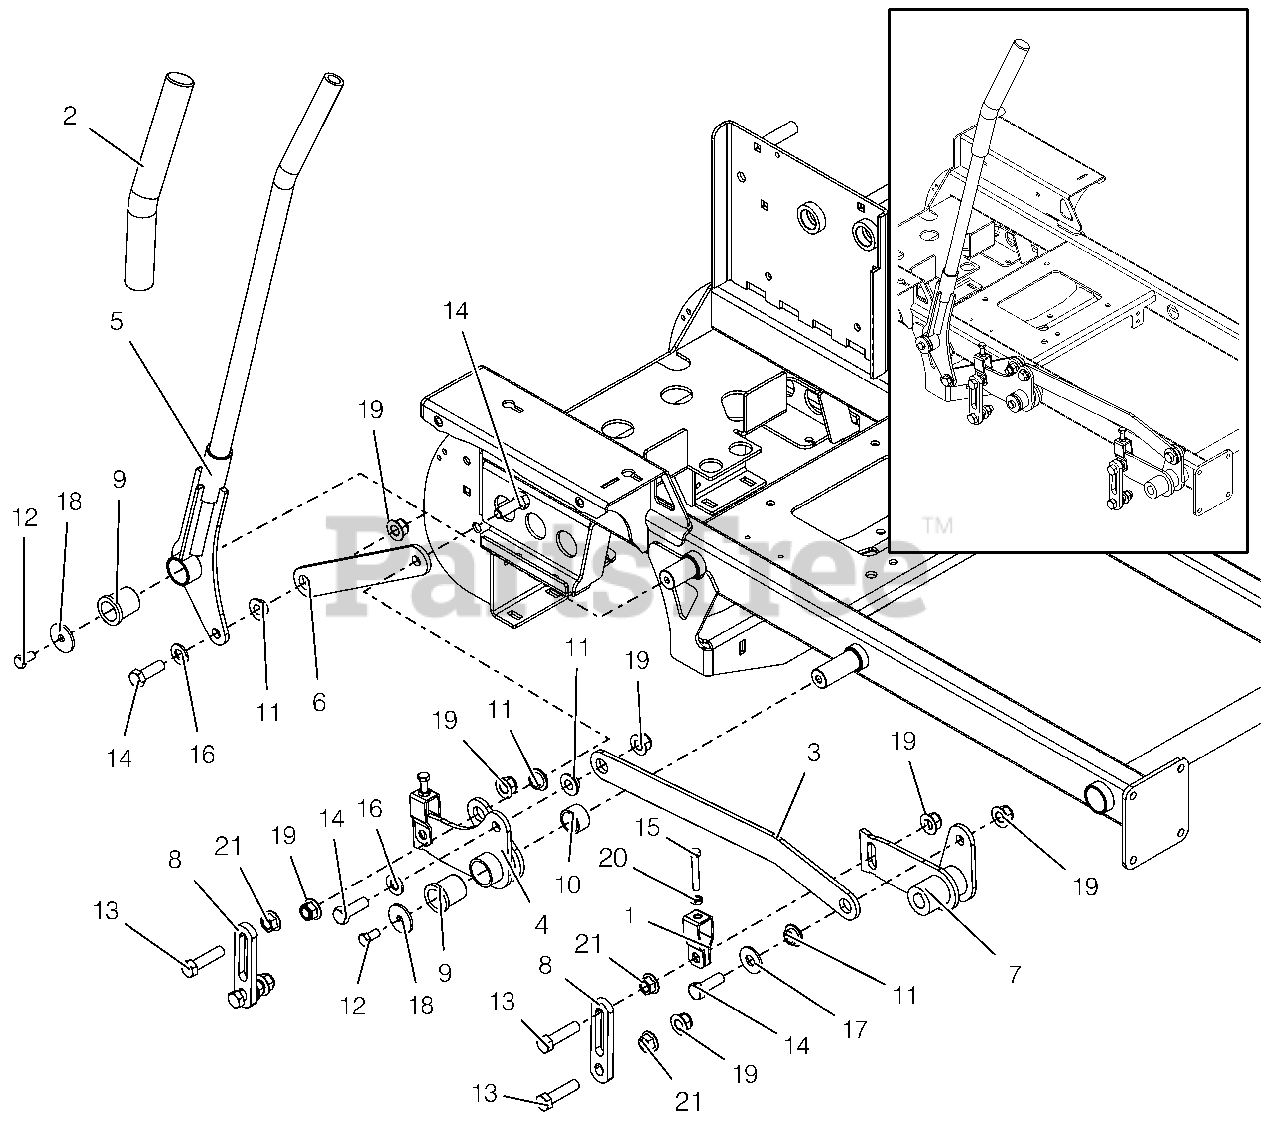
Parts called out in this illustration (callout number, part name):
1	BRKT, DECK LEVELING
2	GRIP, HANDLEBAR 1.00X1.38X11.3
3	PLATE, DECK ARM
4	WLDMT, REAR DECK ARM
5	WLDMT, DECK LIFT HANDLE
6	LINK, DECK LIFT HANDLE
7	WLDMT, RH FRONT DECK ARM
8	LINK-DECK LIFT - SHORT
9	BSHG-FLG 1.00X1.25X1.50X1.50
10	BUSH, SLV 1.00 X 1.25 X .75
11	BSHG, FLG .515X.750X.360X1.12
12	@BLT-HEX .38-16X.75 GR5 YWZC
13	@BLT-HEX .50-13X2.00 GR5 YWZC
14	@BLT-HEX .50-13X1.50 GR5 YWZC
15	BLT-HEX .312-18X2.00 FTH GR5YZ
16	@WSHR-FL-STL.531X1.06X.095YWZC
17	@WSHR-FL-STL.563X1.38X.109YWZC
18	WSHR-FL-STL .380X1.50X.125YWZC
19	@NUT-LK-NYL-FLG .50-13 YWZC
20	NUT- JAM .312-18 YWZC
21	NUT-SPNLK-FLG .50-13 YWZC
